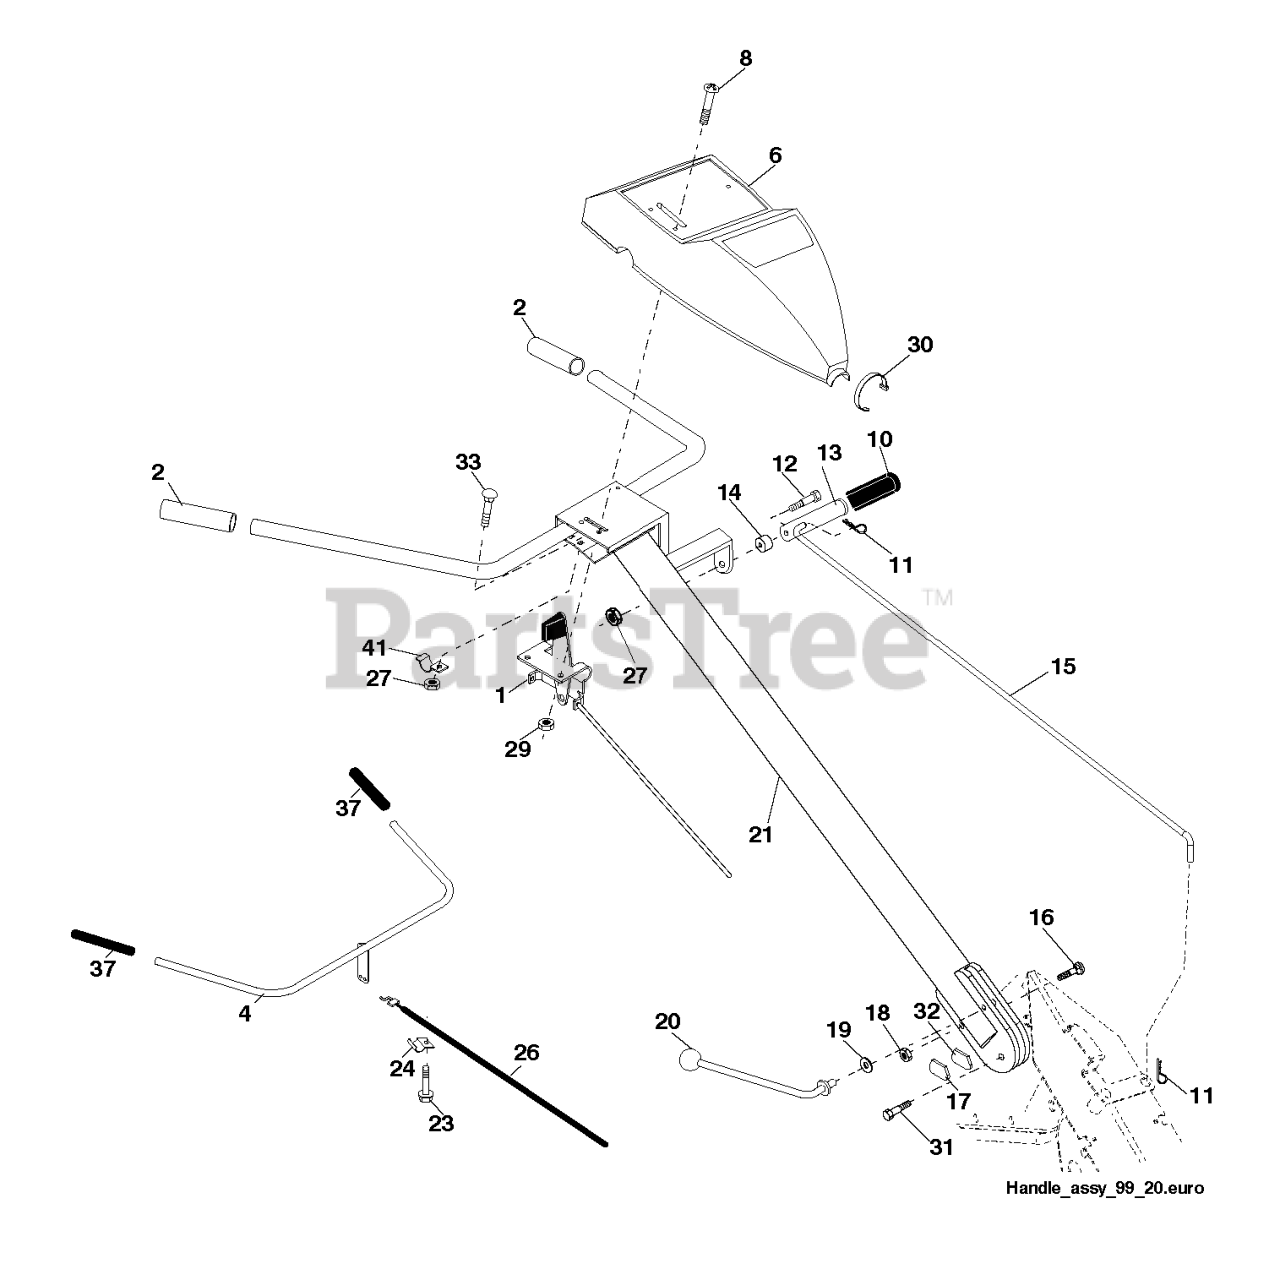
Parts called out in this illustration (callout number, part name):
1	THROTTLE.CONTROL.
2	GRIP.1X5.06
4	CONTROL BAR ASSY
6	PANEL.CONTROL.ORANGE.MS668
8	SCREW.PNHD.10-24
10	GRIP T
11	RETAINER M
12	SHOULDER BOLT ST
13	HANDLE.SHIFT.TILLER
14	GROMMET.RUBBER.CRT.TILLER
15	ROD.SHIFT.YARD PRO.UNIVERSAL.
16	BOLT D
17	LOCK.HANDLE.CRT
19	WASHER CRT
20	LEVER.LOCK.CRT
21	HANDLE.ASM.TILLER.GREY.
23	TAPPING SCREW
24	CONDUIT.CLIP.PLATED
26	CABLE.CLUTCH
27	NUT T
29	NUT **
30	TIE CABLE CRT
31	BOLT.PIVOT
32	LOCK HANDLE
37	GRIP BAR CRT(1)
41	CLAMP.BAR.CRT.BLACK
